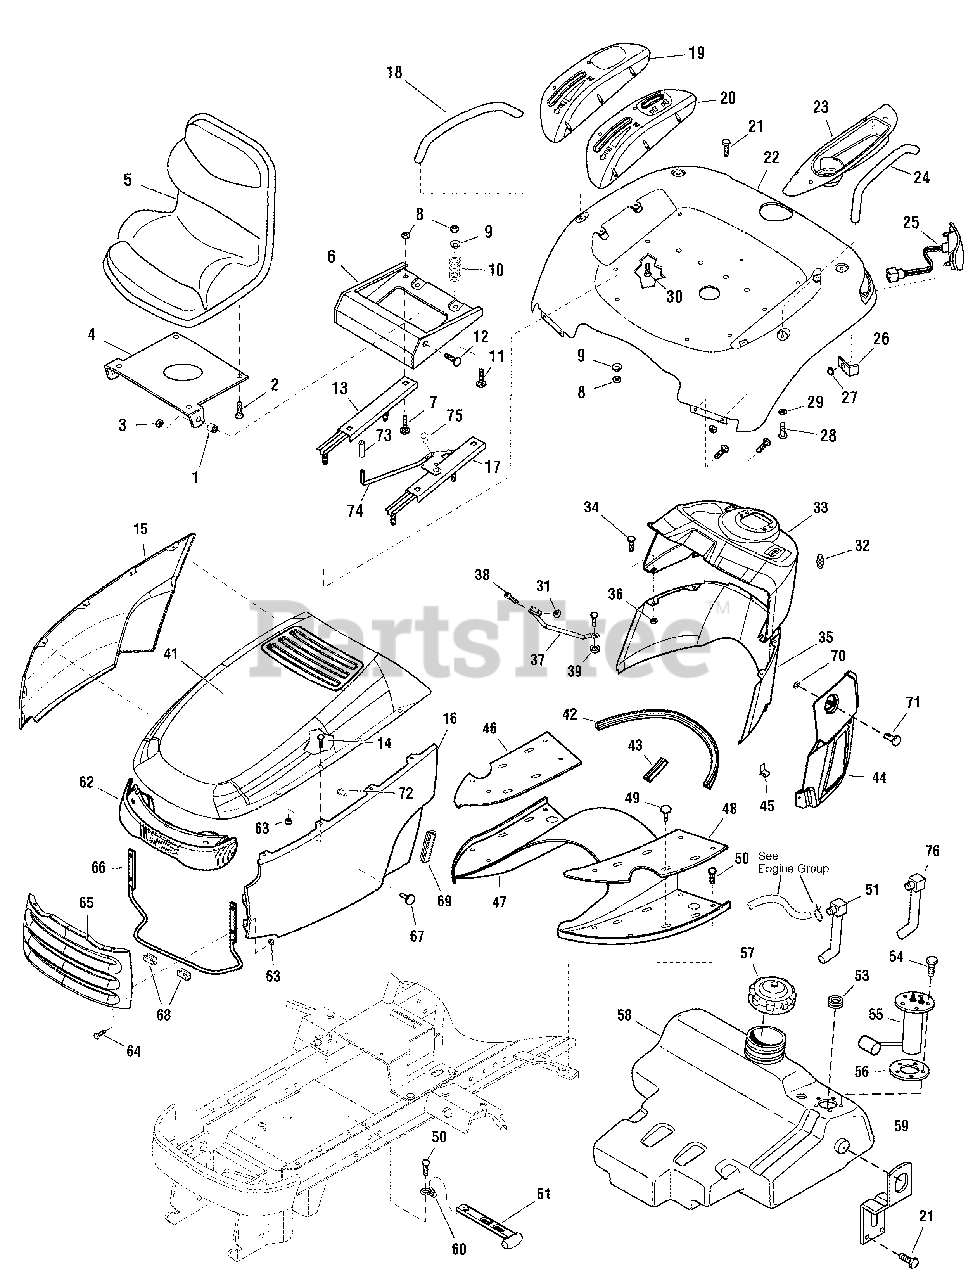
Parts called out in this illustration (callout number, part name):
2	SCREW, Hex, Flange Whiz Lock, Dog Point, 5/16-18 x 1
3	NUT, Hex, Flange ESNA Lock, Black 3/8-16
4	PAN, Seat
5	SEAT, Black
6	SUPPORT, Seat Lower
7	CARRIAGE BOLT, Black, 5/16-18 x 3/4
8	NUT, Nut, Flange Lock, ESNA, 5/16-18
9	WASHER, Spring, 5/16 x 1 1/4
10	SPRING, Seat
11	BOLT, Carriage, Short Neck, 5/16-18 x 1
12	CARRIAGE BOLT, Black, 3/8-16 x 1
13	SLIDE, Seat
14	CAPSCREW, Hex, Head, 1/4-20 x 5/8
15	PANEL, Side R.H., Legacy XL
16	PANEL, Side L.H., Legacy XL
17	SLIDE, Seat, L.H.
18	HANDLE, Grab, RH, Black
19	POD, Legacy XL, 2WD
20	POD, Legacy XL, 4WD
21	CAPSCREW, Hex, Washer Head, Taptite, Black, 5/16-18 x 3/4
22	DECK, Seat, Legacy XL
23	POD, Legacy XL, L.H.
24	HANDLE, Grab, L.H., Black
25	TAIL LIGHT ASSEMBLY
26	CLIP, "L"
27	NUT, Push, Black, 5/16
28	CAPSCREW, Hex Head, Black, 5/16-18 x 5/8
29	WASHER, Black, 5/16
30	CAPSCREW, Hex Washer Head, #12-24 x 5/8
31	NUT, Nylock, # 10-24
32	PLUG, Dashboard, Diesel
33	DASH, Upper, Black, Diesel
34	BOLT, Carriage, 1/4-20 x 5/8
35	DASH, Lower, Black, Diesel
36	NUT, Hex, KEPS, Black, 1/4-20
37	ROD, Dash Support
38	SCREW, Phillips, Pan Head, #10-24 x 1
39	NUT, Hex, Keps, Black, 5/16-18
41	HOOD & SCREEN ASSEMBLY
42	EDGING, Rubber, Black, 23" Long
43	EDGING, Rubber, Black, 2-5/8" Long
44	COVER ASSEMBLY, Dash, Black
45	CLIP, "U"
46	PAD, Footrest, R.H.
47	TUNNEL, Legacy XL
48	PAD, Footrest, L.H.
49	FASTENER, Panel
50	CAPSCREW, Hex, Washer Head, Taptite, Black, 1/4-20 x 1/2
51	ELBOW & TUBE ASSEMBLY
54	SCREW, Pan Head, Torx, SEMS, #10-32 x 1/2
55	SENDER, Fuel
57	CAP, Fuel, Diesel
58	TANK, Fuel, Diesel
59	SUPPORT, Fuel Tank
60	HOOK
61	STRAP, Hood, Black Rubber
62	HEADLIGHT ASSEMBLY
63	NUT, Hex, Flange Whiz Lock, Black, 1/4-20
64	CAPSCREW, Hex, Whiz Lock, Black, 1/4-20 x 1
65	GRILL, Legacy XL (Red)
66	ROD, Hood Hinge
67	SCREW, Binding
68	CLIP, Hood
69	EDGING, Side Panel
70	NUT, Push
71	SCREW, Quarter Turn
72	SCREW, Hex, Serrated Flange
73	GRIP, Black Vinyl
74	ROD, Seat Slide
76	TUBE ASSEMBLY, Fuel With Screen
